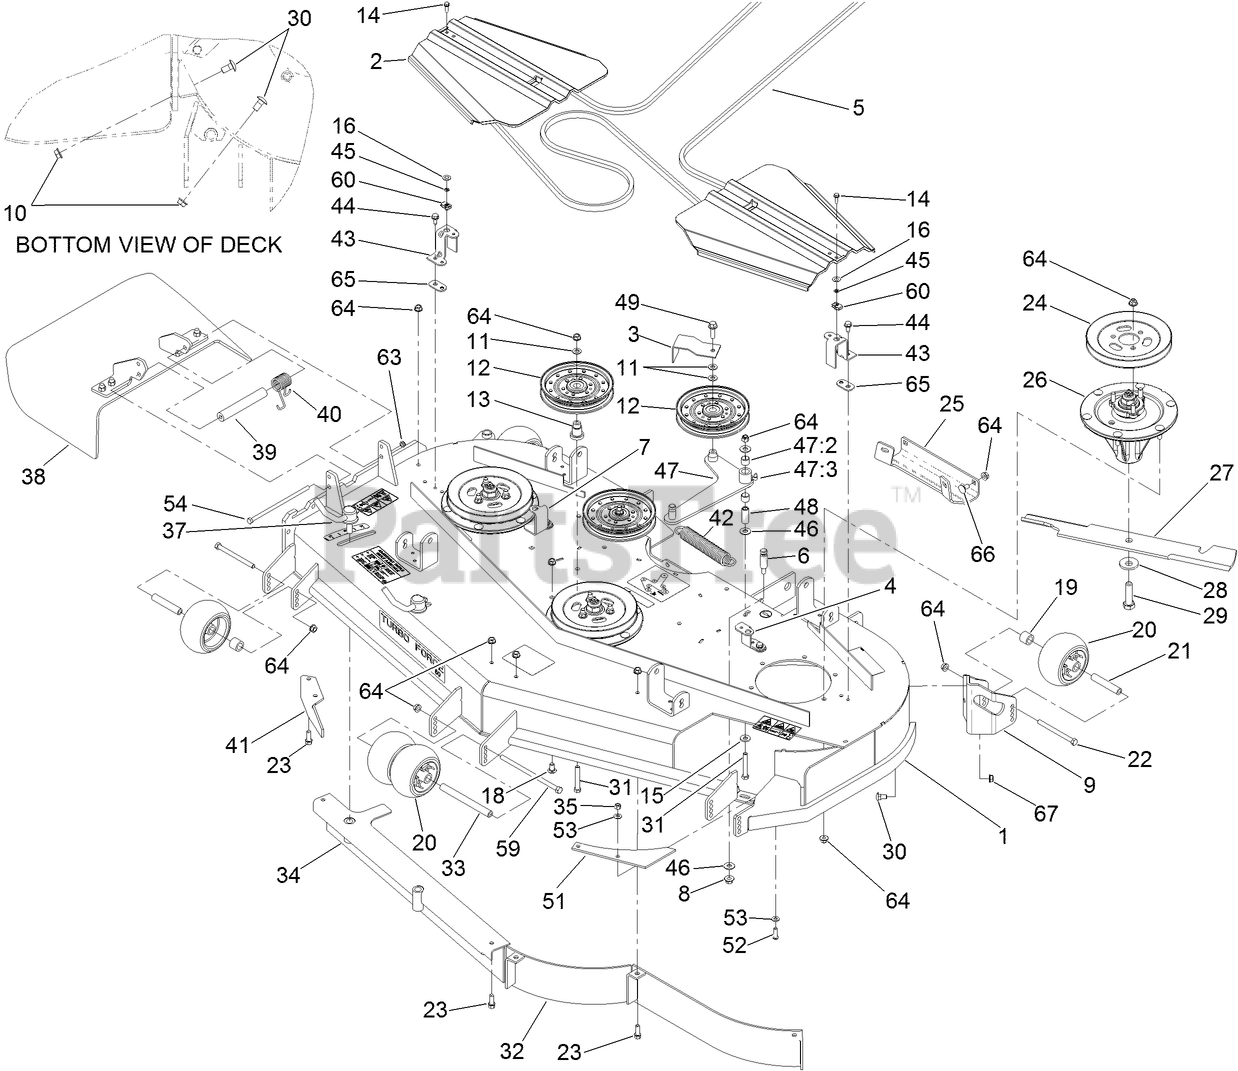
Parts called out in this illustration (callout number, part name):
2	COVER-BELT
3	GUIDE-BELT
4	BRACKET-COVER, TALL
5	BELT-V
6	PIN-THREADED, SPRING ANCHOR
7	BRACKET-COVER
8	NUT-HF
9	MOUNT-WHEEL, LH
10	NUT-HHF, WHIZ
11	WASHER-FLAT
13	MOUNT-PULLEY
14	SCREW-HWH
15	WASHER-BELLEVILLE
16	WASHER-THRUST
18	SCREW-CARR
19	TUBE-SPACER
20	ROLLER-SCALP, ANTI
21	TUBE-SPANNER
22	SCREW-HH
24	PULLEY
25	PLATE-SKID
26	SPINDLE ASM
27	BLADE-HI FLOW
28	WASHER-BLADE BOLT, HEAVY
29	SCREW-BLADE
30	SCREW-HH
31	SCREW-HH
33	SPACER-WHEEL
35	NUT-LOCK, NI
37	LEVER ASM
38	RUBBER DEFLECTOR ASM
39	SPACER
40	SPRING-TORSION
41	BAFFLE-DISCHARGE
42	SPRING-EXTENSION
43	BRACKET-COVER
44	SCREW-HWHTF
45	NUT-RETAINER
46	WASHER-FLAT
47	DECK IDLER ARM ASM
47:2	SLEEVE-BEARING
47:3	FITTING-GREASE, 90 DEG
48	BUSHING
49	SCREW-HHF
51	PLATE-TURBO
52	SCREW-HSBH
53	WASHER-SPRING
54	SCREW-HH
59	SCREW-HH
63	NUT-LOCK, NI
64	NUT-HF, NI
65	SPACER-BELT COVER
66	SCREW-CARR
